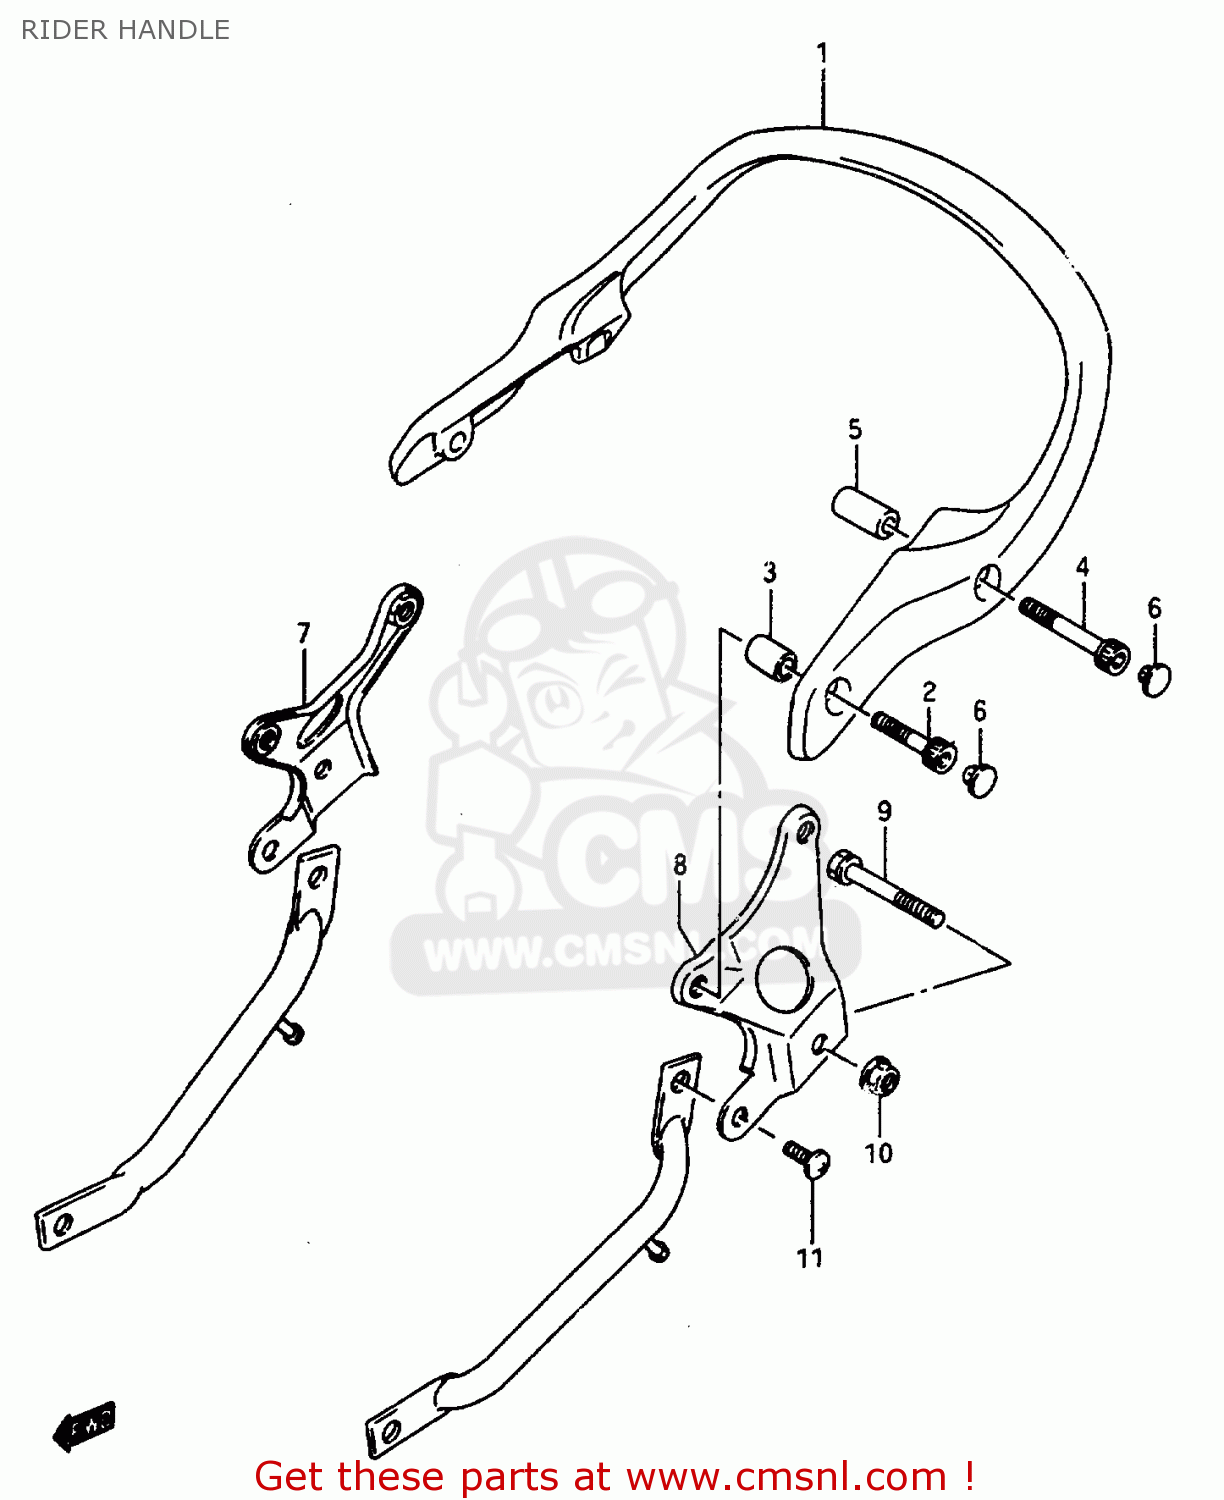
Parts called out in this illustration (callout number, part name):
1	HANDLE,PILLION RIDER
2	BOLT
3	SPACER(8.5X14X21.5)
4	BOLT
5	SPACER(8.5X14X28)
6	CAP(OD:14.5)
7	BRACKET,PILLION RIDER HANDLE,R
8	BRACKET,PILLION RIDER HANDLE,L
9	BOLT
10	NUT
11	SCREW
